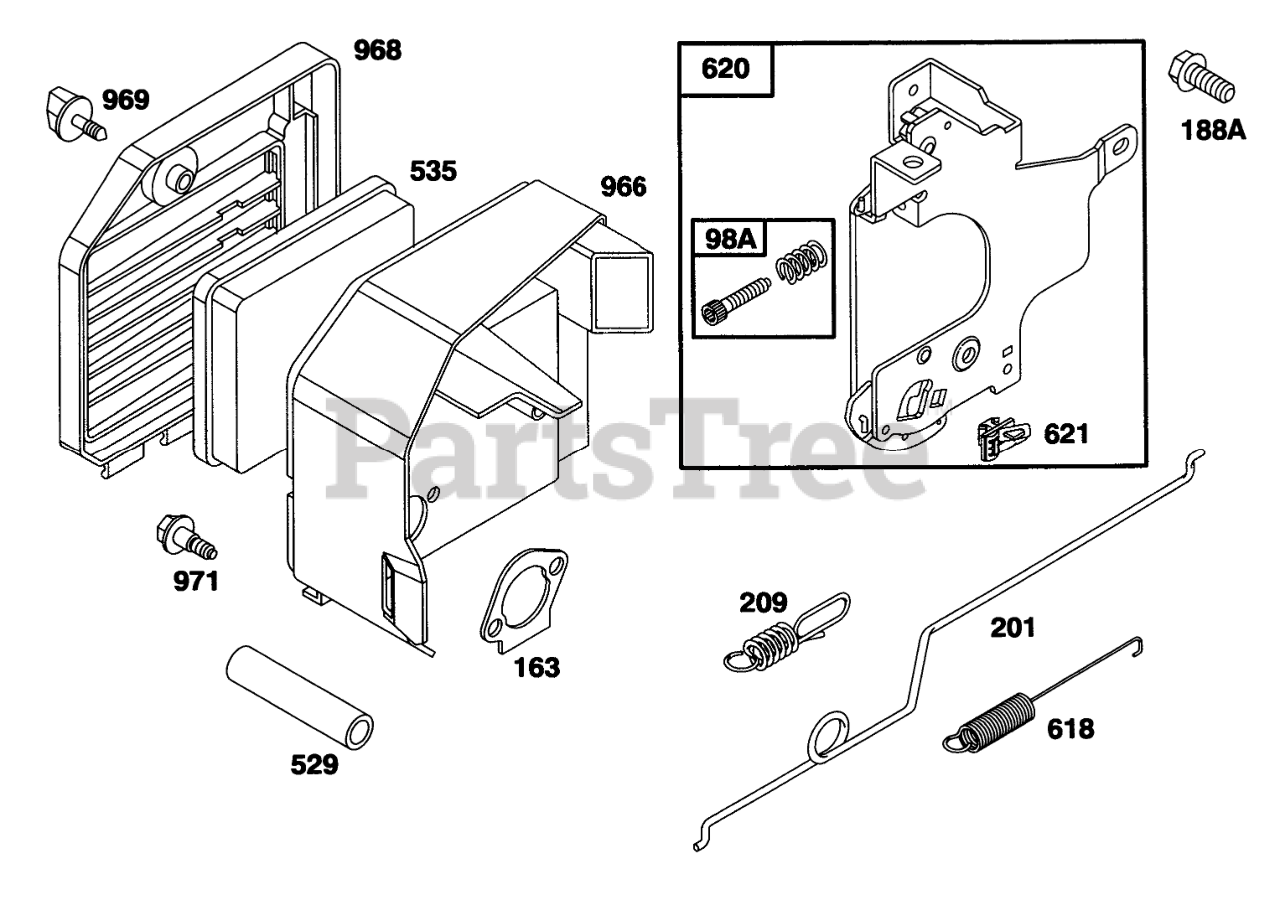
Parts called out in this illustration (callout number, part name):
33	EXHAUST VALVE
98A	SPEED ADJUST. SCREW ASM
163	AIR CLEANER GASKET
188A	Screw-Hex Head
201	GOVERNOR LINK
209	GOVERNOR SPRING
529	BREATHER TUBE
535	FILTER ELEMENT
618	RETURN SPRING
620	CARBURETOR BRACKET
621	STOP SWITCH
966	AIR CLEANER BASE
968	AIR CLEANER COVER
969	AIR CLEANER SCREW
971	AIR CLEANER SCREW
